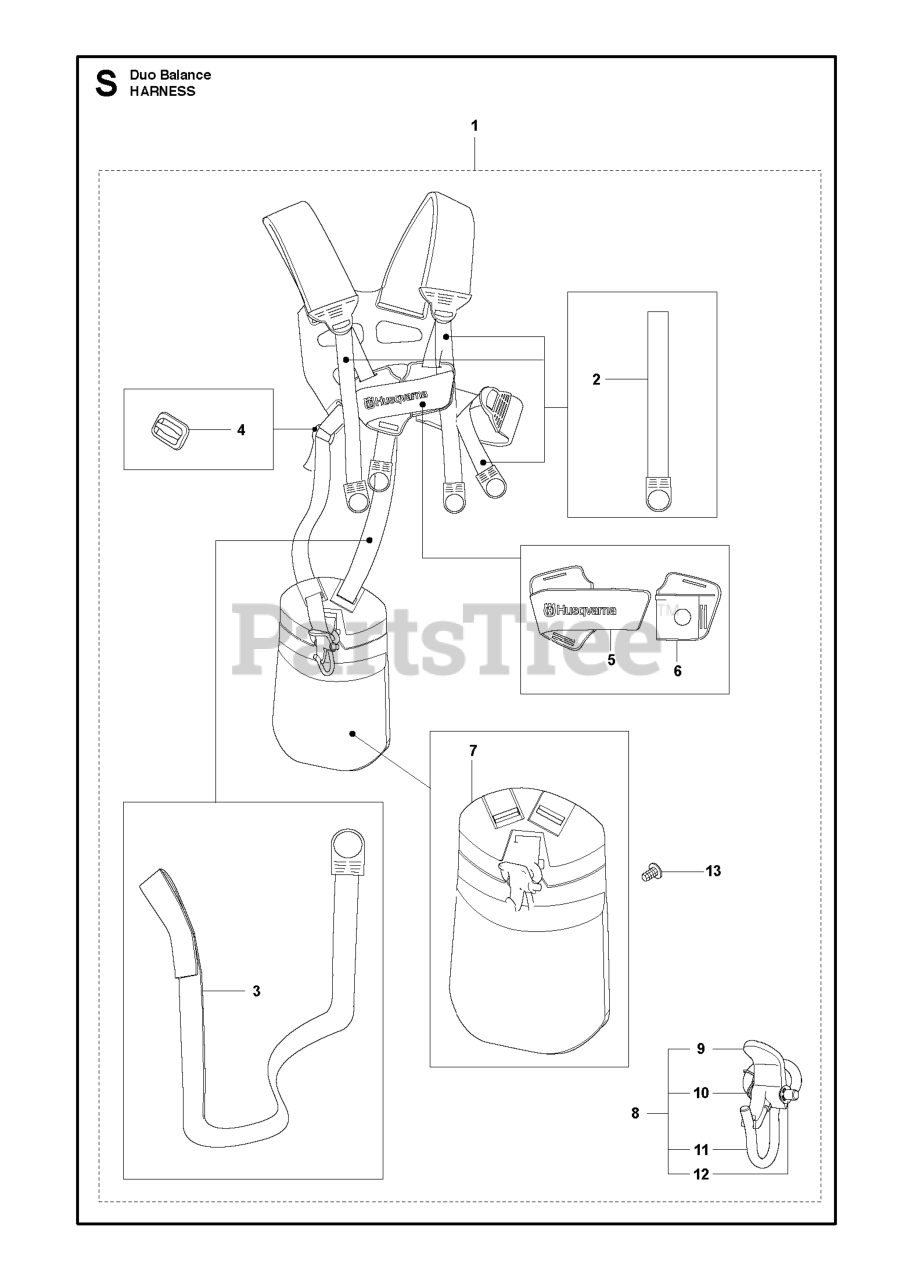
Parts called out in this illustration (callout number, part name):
1	RAIL, FRAME RH
2	DRAWBAR-GT
3	SIDE PANEL LH
4	NUT, CROWNLOCK 7/16-14 UNC
6	DASH VGT, LOWER
7	SCREW, THD CUT 1/4-20 X 1/2
8	SUPPORT, BATTERY
9	PAL NUT LT
14	HOOD ASM PNT
15	LENS
16	COVER ACCESS
17	SCREW
18	GRILLE.ASM.HUSQVARNA.YTGT
19	BOLT
20	BOLT, FIN HEX 3/8-16 X 1
21	NUT
22	PANEL ASM SD RH
23	SCREW 3/8-16 X 1/2
24	FOOTREST RH
25	LENS
27	NUT FIN HEX 1/4-20
28	FOOT REST LH
29	DASH SUPT YP
30	SADDLE.HYDRO.95
31	BRACKET SUPT 1-PC VGT STEERING
34	ENGINE SUPPORT BRKT
35	WASHER 11/32 X 11/16 X 16 GA.
36	BOLT, FIN HEX 5/16-18 X 3/4
37	FENDER
38	WASHER LOCK
39	FRONT AXLE BRACKET
40	BRACKET, SUPPORT AXLE/ENGINE
43	FRONT SUSPENSION BRKT LH
44	FRONT SUSPENSION BRKT RH
45	BRACKET SUSP RH
46	WASHER 9/32 X 3/4 X 16 GA.
47	SCREW
50	BRACKET, CHASSIS FRONT
52	NUT
54	NUT
56	BRACKET ASM, SUSP CHASSIS
58	FENDER BRKT
60	SCREW
63	WASHER 13/32 X 1 X 14 GA.
68	SCREW
70	BELT GUIDE
72	SCREW
74	SCREW
76	WELDNUT
79	SCREW, MACHINE #10-24 X 1/4
80	SPACER, SPLIT
82	NUT #10-24
84	MOWER STOP
86	BOLT, FIN HEX 7/16-14 UNC X 1
90	WASHER
91	RAIL, FRAME LH
92	PLATE, SILKSCREEN DASH
98	BRACKET CHASSIS
99	ROD ASM. BYPASS
100	PLUNGER CAP
101	SCREW THDROL. 3/8-16 X 1-3/4
102	RETAINER SPRING 1"
103	BRACKET LOCK BYPASS
106	SCREW THDROL. HEX HD ZINC MUR
107	LATCH.HOOD.
108	SNAP CAP LT
110	PIVOT ASM GRL/HD
112	NUT
114	BOLT, CARRIAGE 3/8-16 X 1-1/4
115	BUMPER ASM
116	BRACKET BUMPER
117	PLUG PLASTIC
118	WASHER
119	NUT
130	SCREW
131	BRACKET.SUPPORT.HOOD/PANEL.NLA
132	SCREW 10-24X3/8
136	SCREW
138	CUPHOLDER
139	BOLT, SHOULDER 5/16-18 TT
145	WASHER FLAT 13/32 X 7/8 X 16GA
151	SCREW 5/16-18 X 3/4
152	SCREW
153	NUT
154	BOLT HEX FIN 3/8-13 X 1
